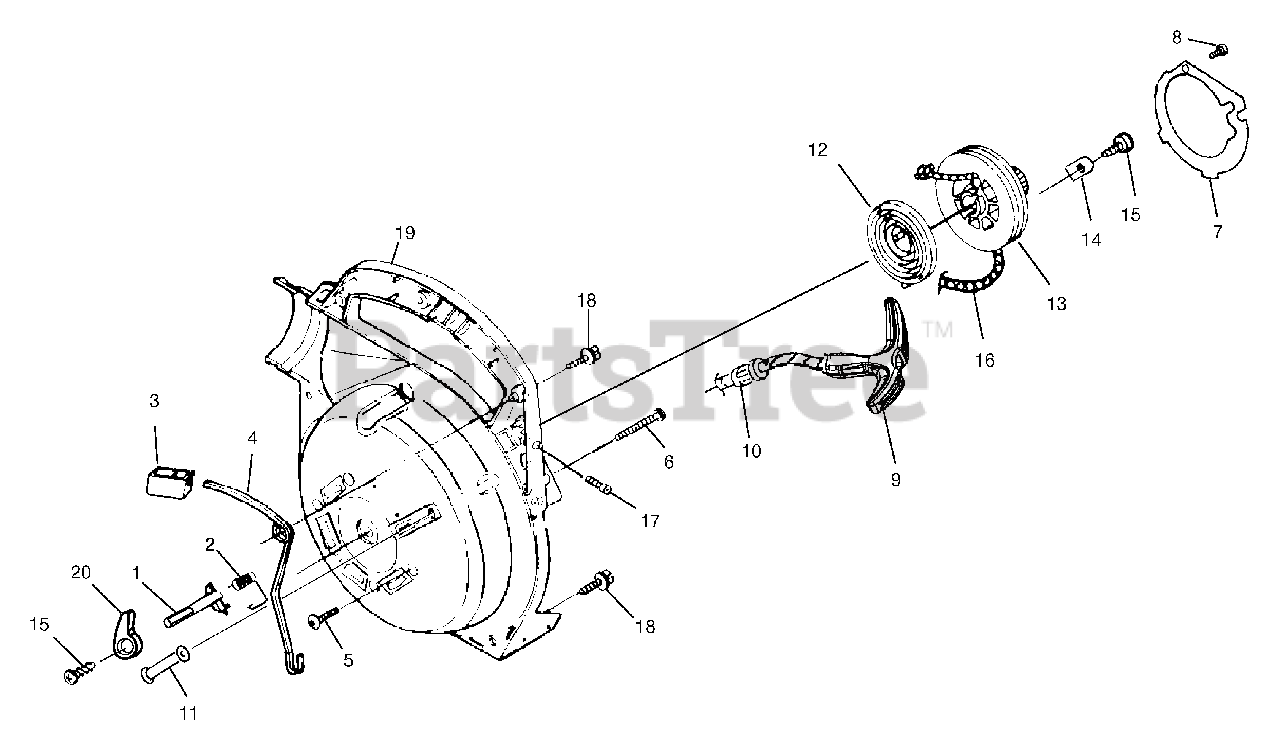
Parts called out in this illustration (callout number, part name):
1	THROTTLE LATCH
2	THROTTLE LATCH SPRING
3	THROTTLE TRIGGER
4	THROTTLE LEVER
5	SCREW (10-24 x 3/4 in.TRUSS HD)
6	SCREW (10 x 1-5/8 in. HEX HD)
7	ROTOR PLATE
8	SCREW (#6 x 1 3/8)
9	STARTER GRIP (YELLOW)
10	BUSHING STARTER
11	STARTER ROPE GUIDE
12	SPRING AND CONTAINER
13	STARTER PULLEY
14	RETAINING BRACKET
15	SCREW (10-24 x 1/2 in. TORX TRUSS HD)
16	STARTER ROPE
17	SCREW (8-32 x 5/8 in. FIL HD)
18	SCREW (10-14 x 3/4 in. TORX TRUSS HD)
19	INNER VOLUTE HOUSING
20	THROTTLE CONTROL KNOB
